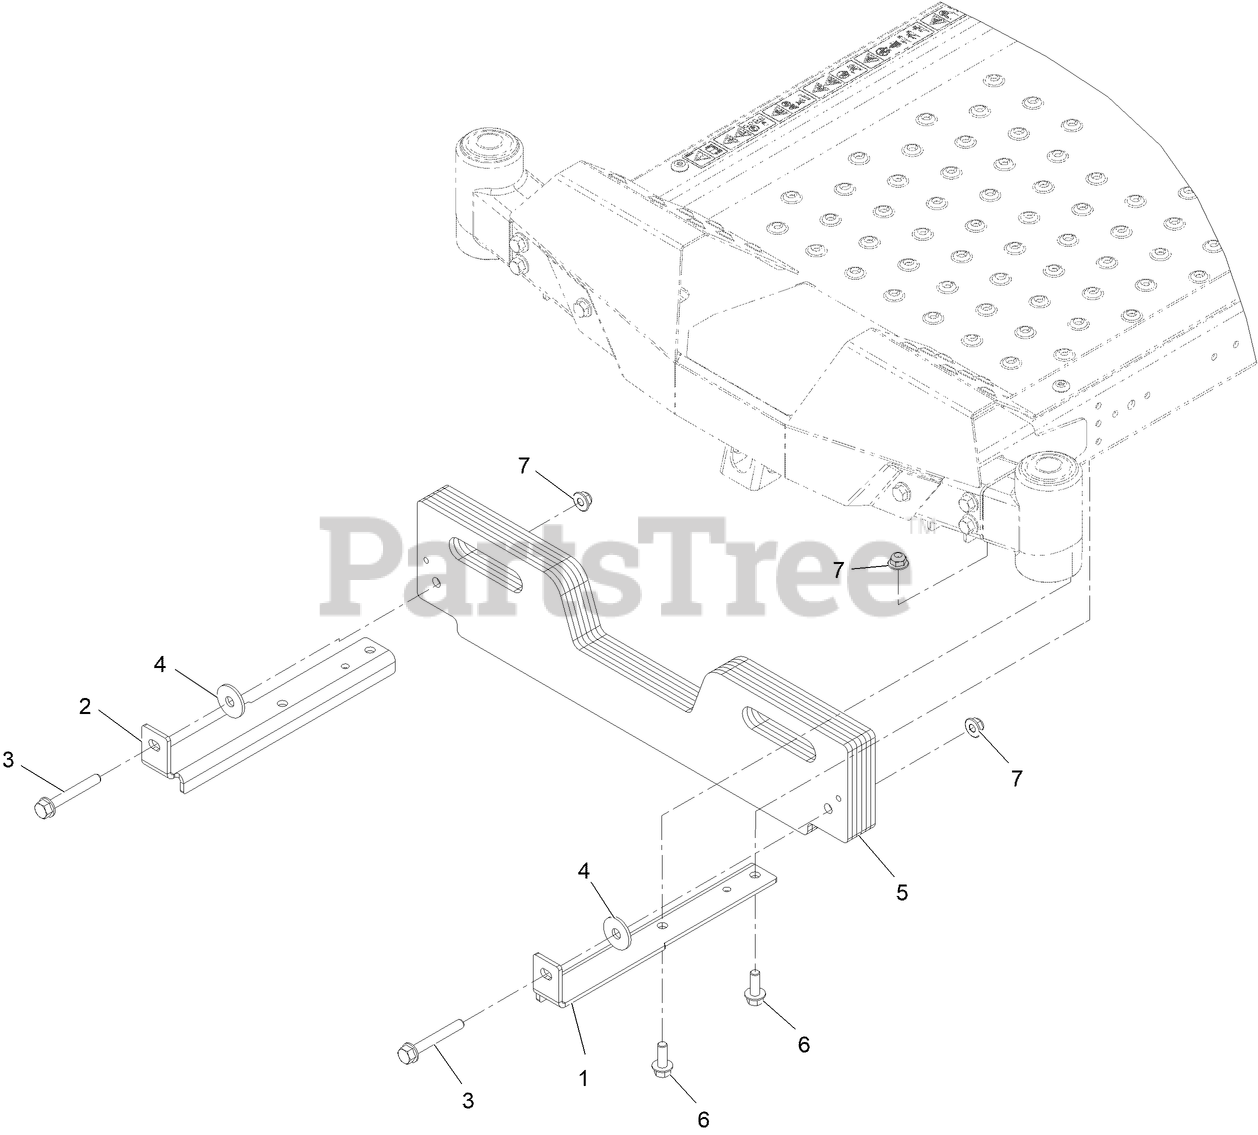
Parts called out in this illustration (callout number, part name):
1	Bracket-Weight, LH
2	Bracket-Weight, RH
3	Screw-Spcl
5	Weight-Bagger
6	SCREW-HHF
7	Nut-HF, NI
